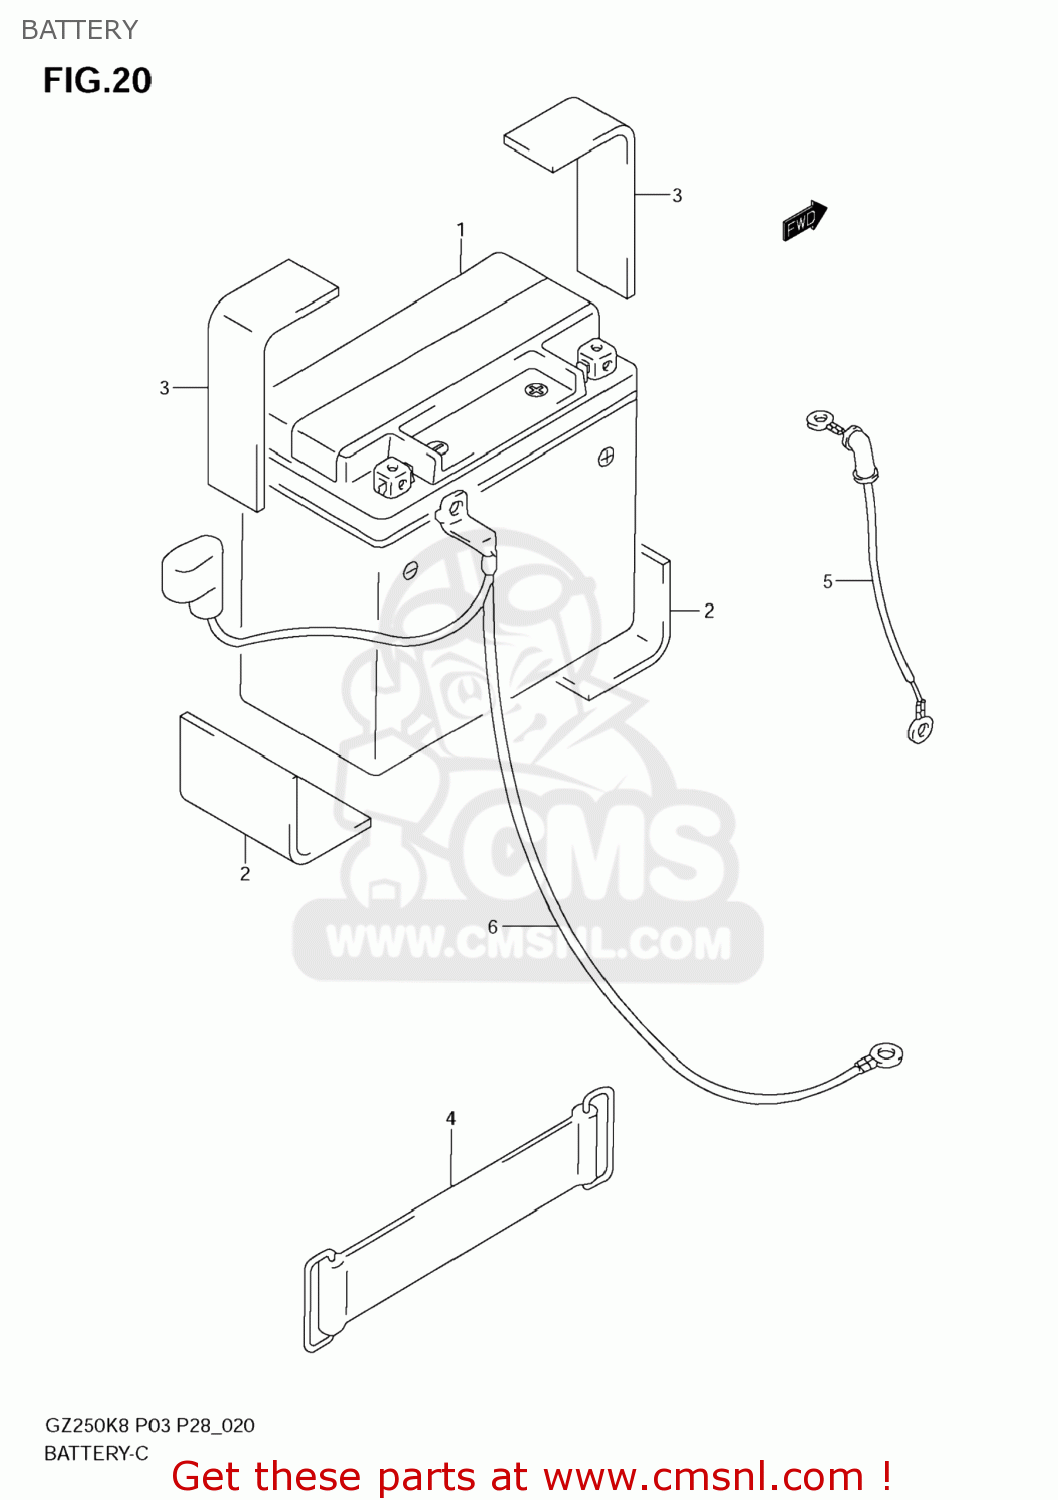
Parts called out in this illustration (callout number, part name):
1	BATTERY ASSY (FTX7L-BS, 12V6A
2	PROTECTOR(170X95X3.0)
3	PROTECTOR (20X90X3)
4	BAND
5	WIRE, BATTERY (+)
6	WIRE,BATTERY MINUS
